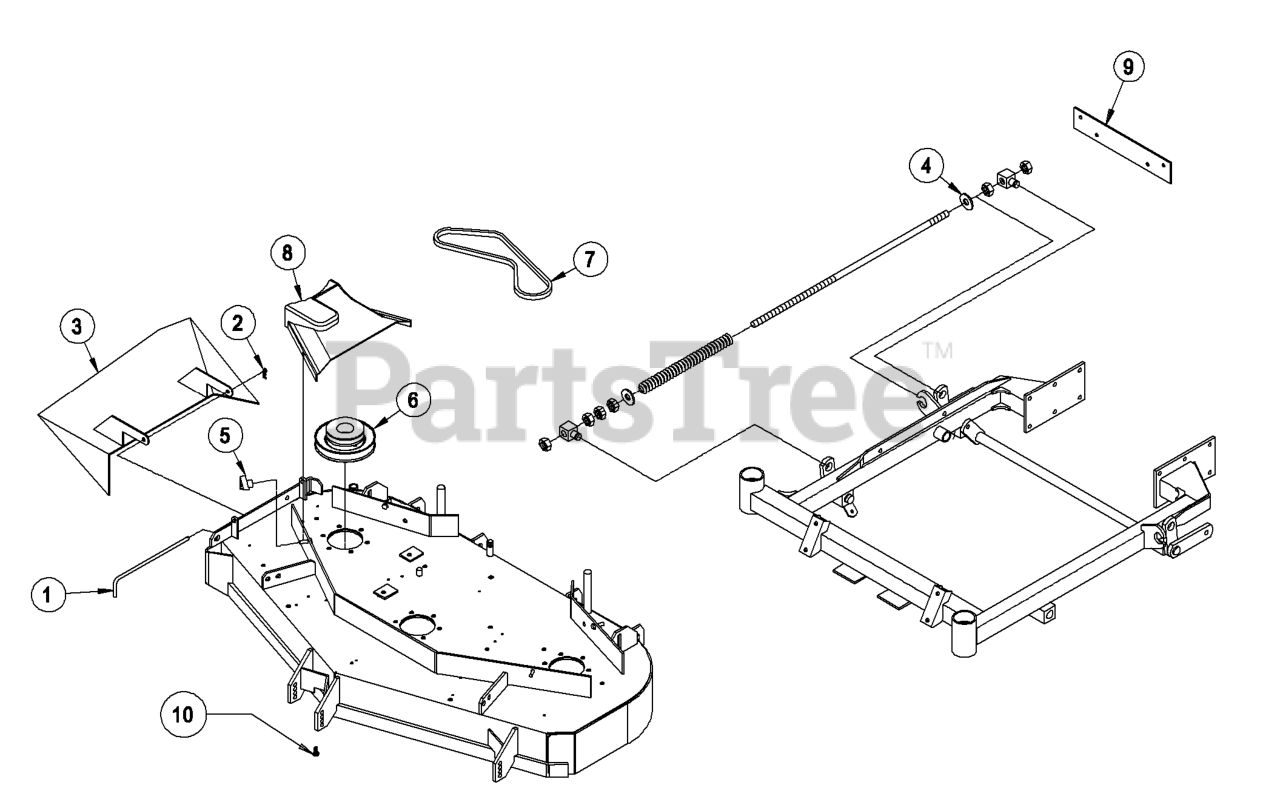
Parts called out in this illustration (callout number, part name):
1	PIN, CHUTE PIVOT PLTD
2	PIN-COTTER
4	WASHER
5	KNOB-3 PRONG
6	SHEAVE, BLOWER DR 48"
7	BELT-BLOWER
8	COVER, BELT 44/48
9	SPACER,COUNTERWEIGH
10	SCREW-HH
